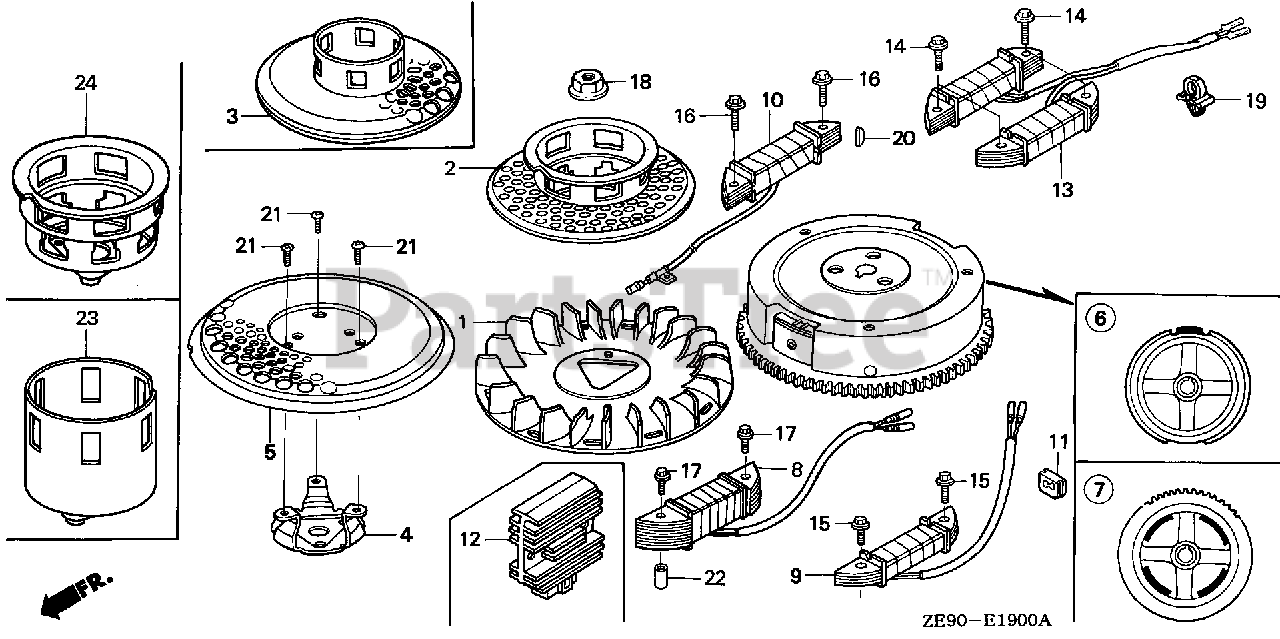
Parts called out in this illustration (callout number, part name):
1	FAN, COOLING
7	FLYWHEEL (SEL-4POLE)
11	GROMMET, WIRE
13	COIL ASSY., CHARGE (10A)
14	BOLT, FLANGE (6X32) (CT200)
18	NUT, SPECIAL (16MM)
20	KEY, SPECIAL WOODRUFF (25X18)
22	COLLAR, EXTENSION
